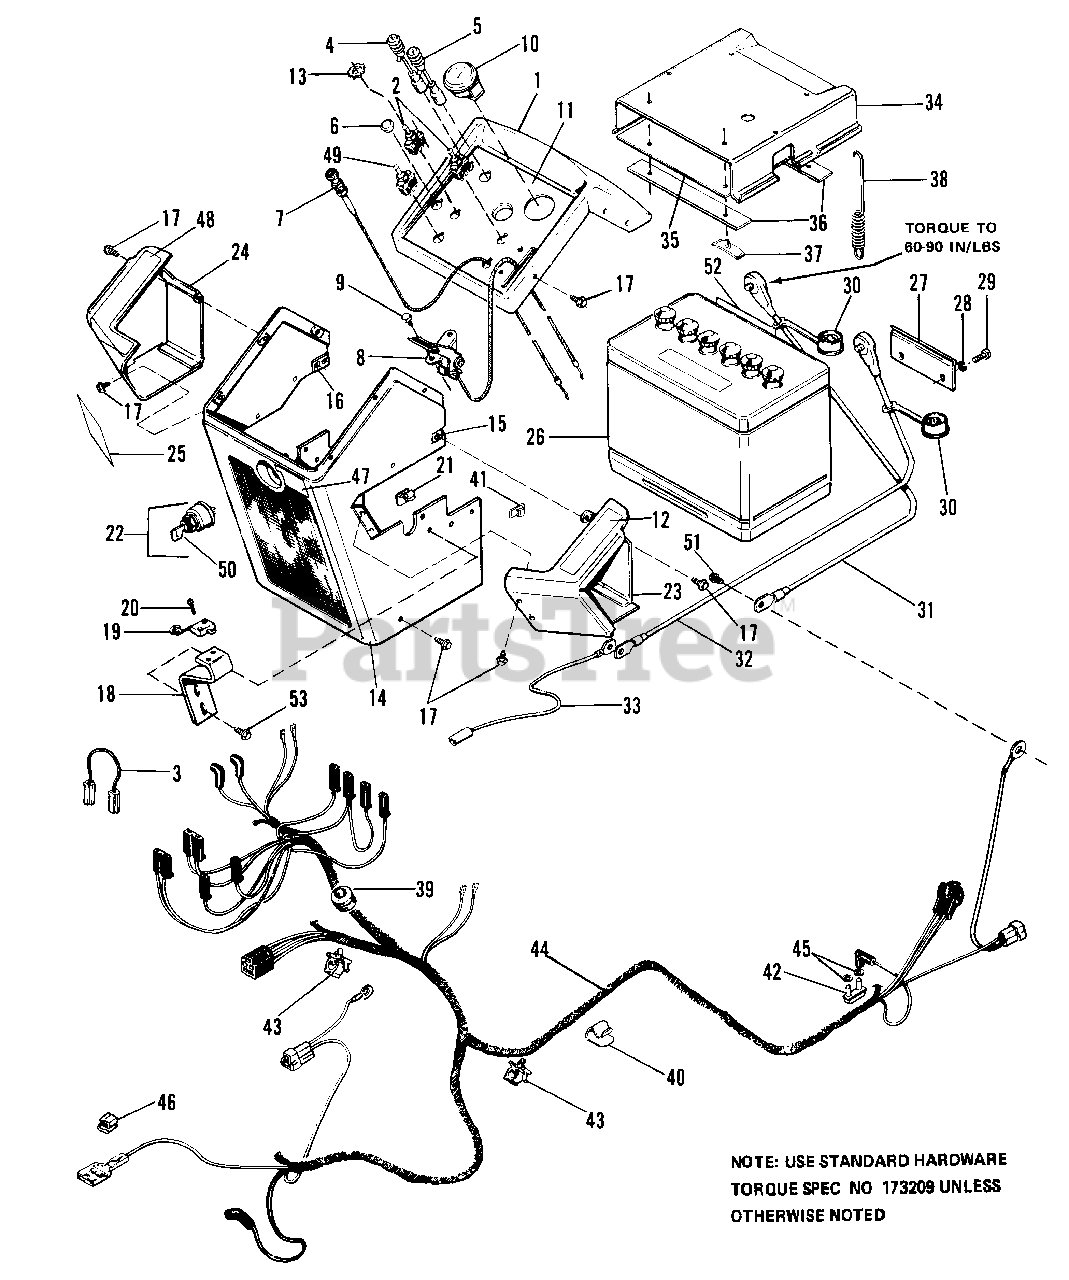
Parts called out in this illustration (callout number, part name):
1	PANEL ASSY
2	SWITCH, Toggle, Clutches
3	WIRE, Jumper
4	LIGHT, Hot
5	LIGHT, Oil
6	BUTTOM, Plug
7	CONTROL, Choke
8	CONTROL, Throttle
9	SCREW, Taptite, 1/4-20 x 5/8
11	DECAL, Dash
12	DECAL, Speed Range
13	LOCKWASHER, In-Tooth, 1/2
14	SUPPORT, Body Assy
15	NUT, Speed, 1/4-20
16	NUT, Speed, 1/4-20
17	SCREW, Taptite, 1/4-20 x 3/8
18	BRACKET, Switch
19	SWITCH, Interlock
20	SCREW, Taptite, No. 4-40 x 5/8
21	CLIP, Speed
22	SWITCH, Ignition
23	PANEL ASSY., R.H.
24	PANEL ASSY., L.H.
25	DECAL, Parking Brake
26	BATTERY KIT
27	CLAMP, Battery
28	LOCKWASHER, 5/16
29	CAPSCREW, Hex, 5/16-18 x 3/4
30	CAP, Protective
31	CABLE, Battery,
32	CABLE, Battery,
37	CLIP, Speed
41	CLIP, Speed
42	BREAKER, Circuit
44	HARNESS, Wiring
45	WASHER, Paper
46	CLIP, Fuse
47	DECAL, Ignition
48	DECAL, Lift
49	SWITCH, Toggle, Headlight
50	KEY RING, (set of 2)
51	SCREW, 5/16-18 x 3/8
52	DECAL, Battery
53	SCREW, Taptite, 1/4-20 x 1/2
